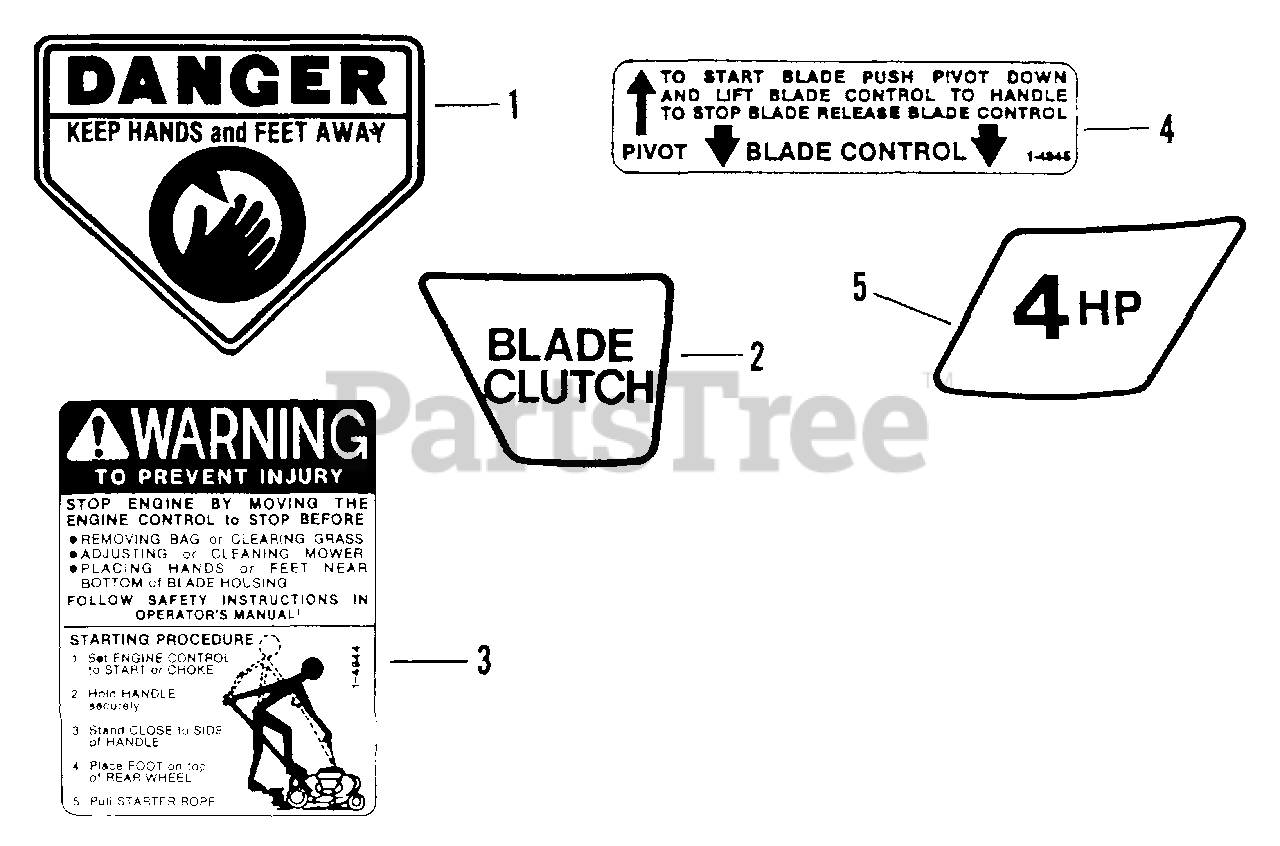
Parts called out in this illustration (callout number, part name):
1	DECAL, CPSC (Danger)
2	DECAL, Blade Clutch
3	DECAL, Warning
4	DECAL, Blade Start
5	DECAL, 4 HP
